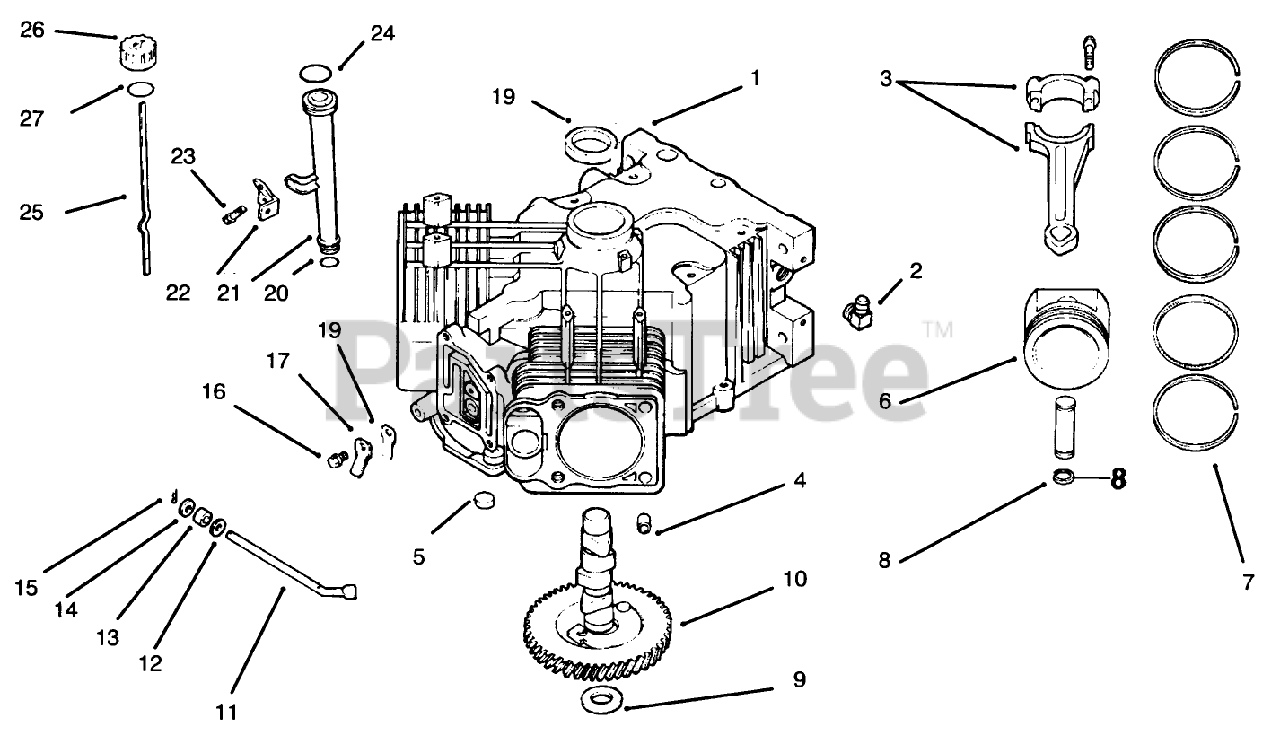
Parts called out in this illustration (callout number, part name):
1	Miniblock
2	Fitting
3	Rod-Connecting (Std)
4	Pin-Dowel
6	Piston w/Ring Set (Std.) (Incl. Ref. # 4-6)
7	Set-Ring (Std)
8	Retainer-Piston Pin
9	Shim-Camshaft
10	Camshaft
11	Shaft-Governor Cross
12	Washer
13	Seal
14	Washer
15	Pin-Hitch
17	Retainer-Reed (Only On: 72103)
18	Beed-Breather
19	Seal-Oil
20	O-Ring-Lower Fill Tube (Only On: 72042, 72063, 72062, 72043)
21	Tube-Oil Fill (Only On: 72103, 72083)
22	Bracket-Oil Fill Tube (Only On: 72103)
24	O Ring-Upper Fill Tube (Only On: 72103)
25	Dipstick INC 26-27 (Only On: 72103, 72083)
26	Kit-Oil Fill Cap (Incl. Ref. #7)
27	ORing
